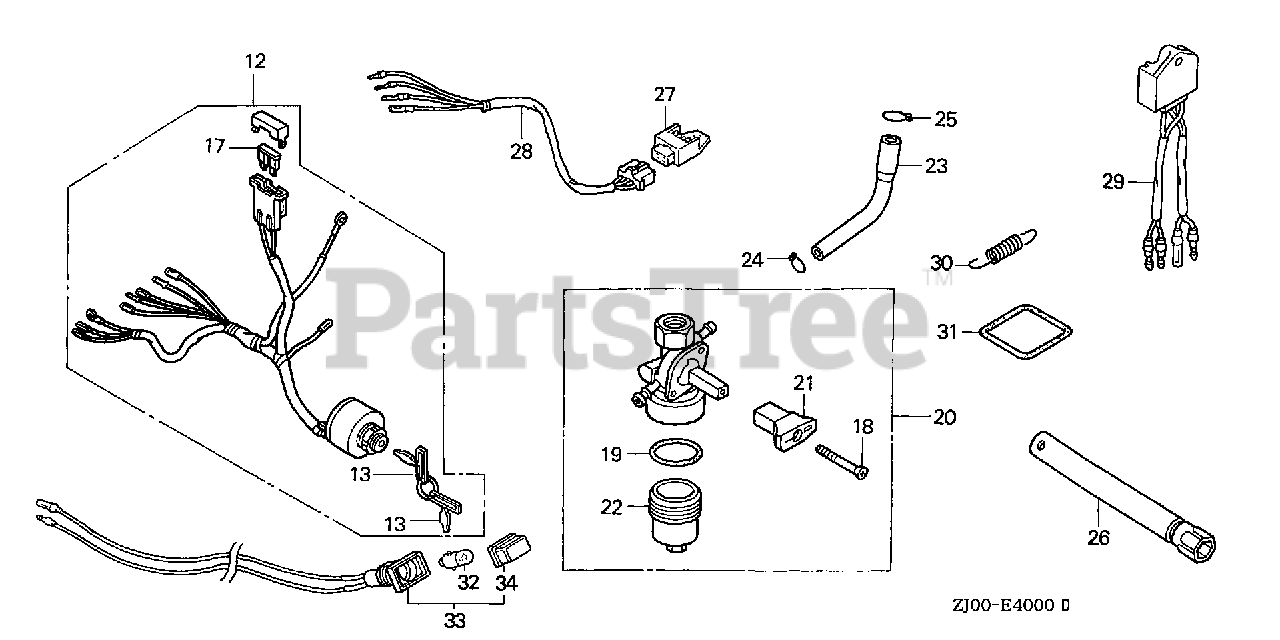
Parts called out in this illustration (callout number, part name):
26	WRENCH, SPARK PLUG
32	BULB, WEDGE BASE (12V/2W)
33	SOCKET ASSY., LAMP (RED)
34	LENS (RED)
